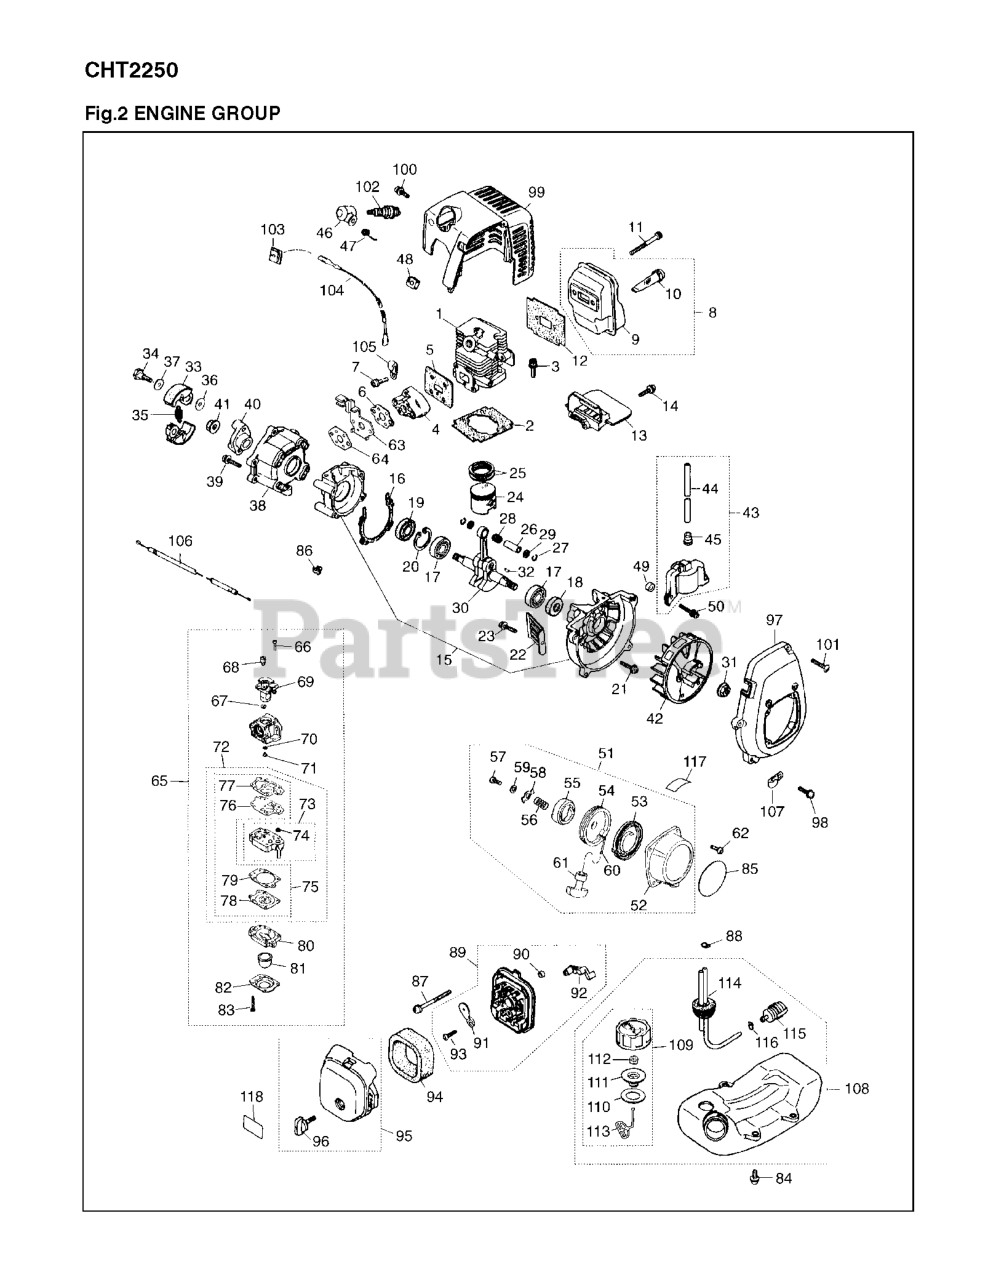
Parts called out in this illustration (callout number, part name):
1	CYLINDER
4	INSULATOR
8	MUFFLER ASSEMBLY
10	ARRESTER
11	BOLT, M5 x 50 (RPLS 125230550)
15	CRANKCASE-C
19	SEAL
25	RING
26	PIN.PISTON
30	CRANKSHAFT (RPLS 560042000)
31	NUT
32	KEY
41	NUT
45	CAP
48	GROMMET
49	SPACER
51	RECOIL-A
53	SPRING.SPIRAL
65	CARBURETOR ASSY
67	RING
68	SWIVEL
72	REBUILD KIT
73	CARBURETOR BODY
75	GASKET KIT
82	1OVER
85	LABEL RECOIL
88	CLIP
91	PLATE.CHOKE
93	SCREW
97	COVER.FAN
105	CLAMP
107	CLAMP
108	TANK ASSY
111	HOLDER-A
114	PIPE COMPLETE
116	CLIP
